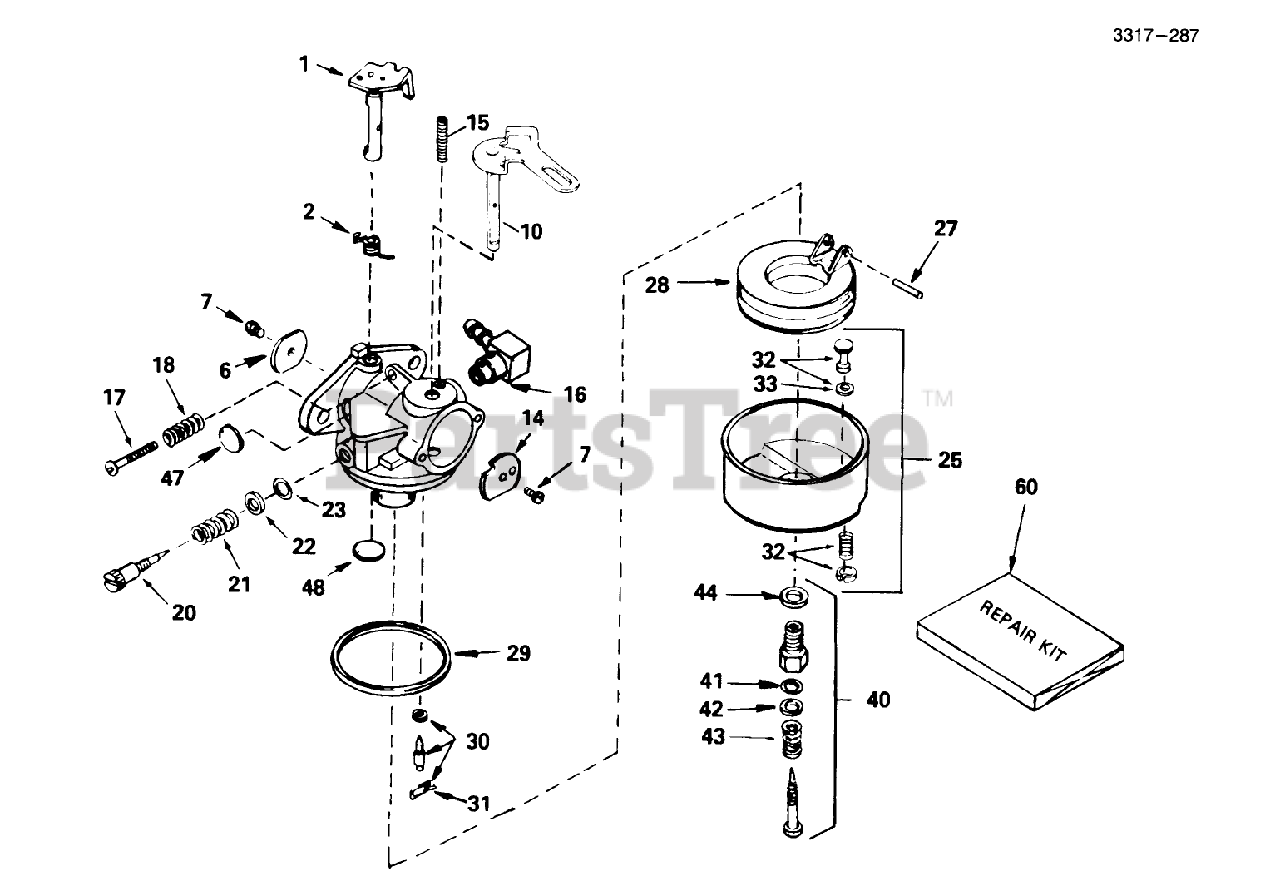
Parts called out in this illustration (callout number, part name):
1	Throttle Shaft and Lever ASM
2	Spring-Return, Throttle
6	Shutter-Throttle
7	Screw-Shutter
10	Choke Shaft and Lever Asm
14	Shutter-choke
15	Spring-Positioning, Choke
16	Fitting-Fuel
17	Screw-Throttle Crack Screw / Idle Speed
18	Spring-Tension
20	Screw-Idle
21	Spring-Tension
22	Washer
23	ORing
25	Float Bowl Asm. (Incl. Ref. # 32, 33)
27	Shaft-Float
28	Float
29	O Ring-Bowl, Float
30	Inlet Needle, Seat Clip Assy. (Incl. No. 13)
31	Clip-Spring
32	Bowl Drain ASM
33	Gasket-Plunger, Drain
40	Adjustment Screw Assy., Main (Incl. Nos. 5A, 21 23)
41	ORing
42	Washer
43	Spring
44	Washer-Bowl Nut
47	Plug-Welch, Idle Mixture Well
48	Plug-Welch, Atmospheric Vent
60	Repair Kit (Incl. items marked *)
